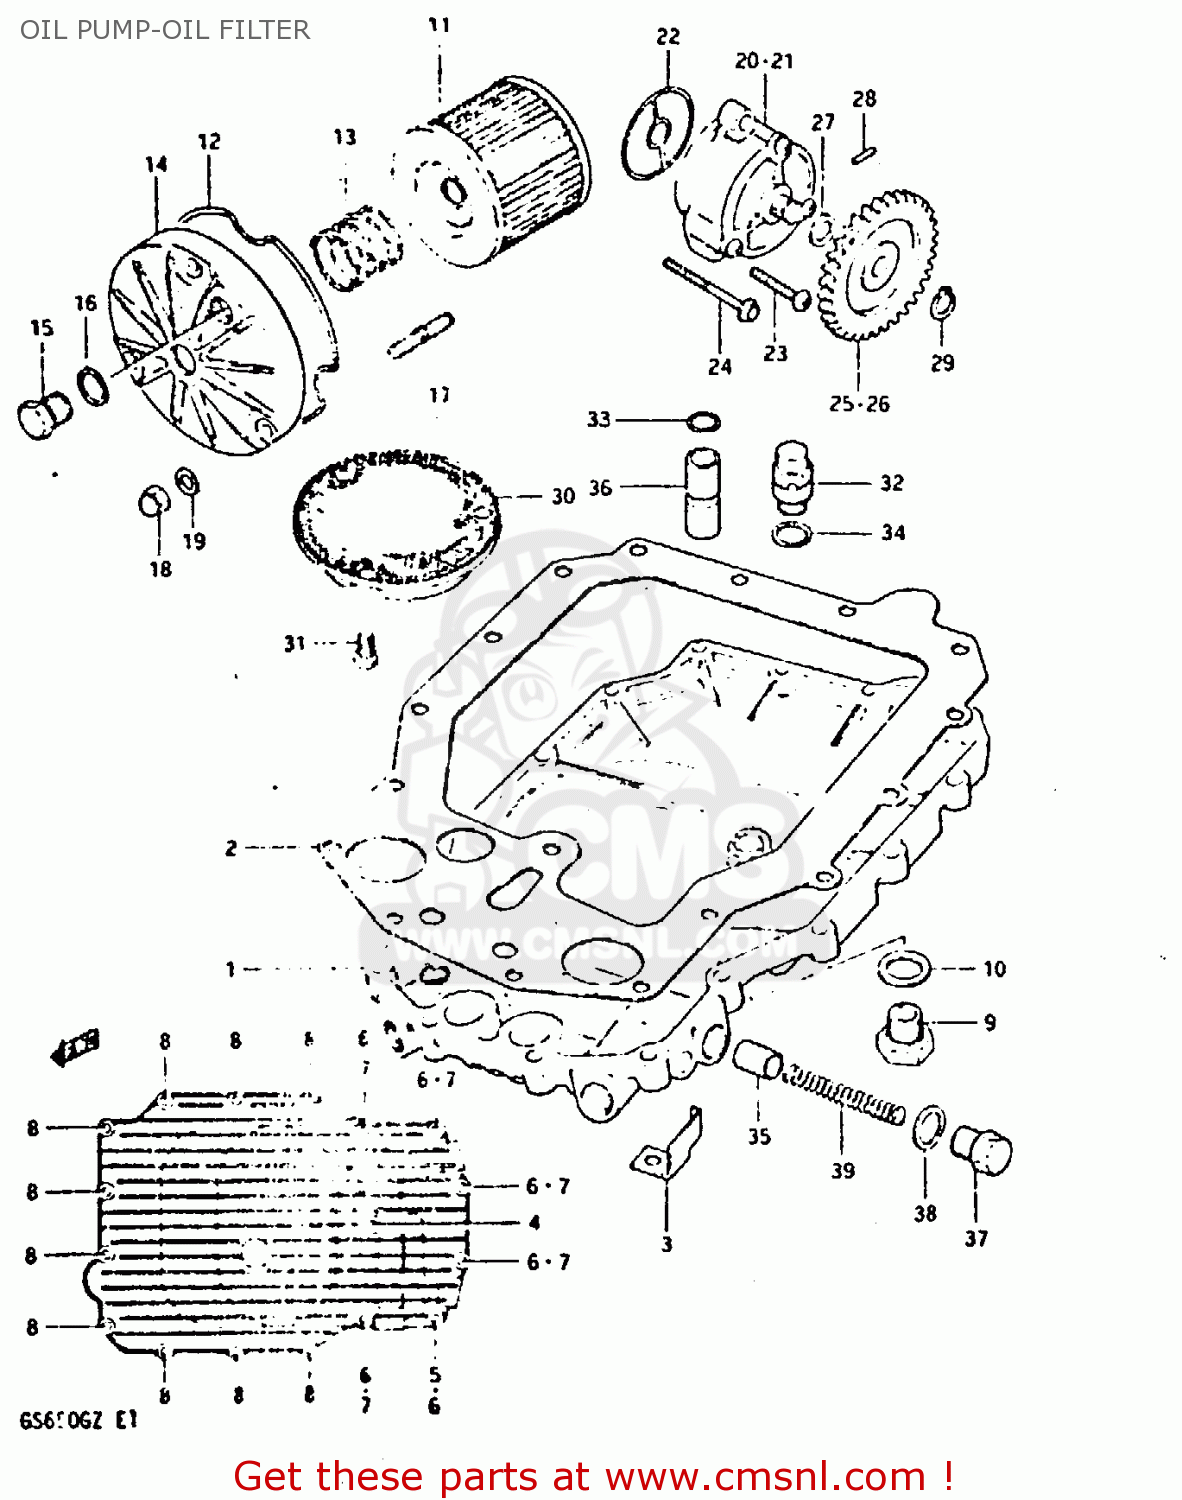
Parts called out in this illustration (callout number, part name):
1	PAN, OIL
2	GASKET,OIL PAN (MCA)
3	PLATE, OIL PAN
4	BOLT 6X35
5	BOLT
6	BOLT
7	BOLT
8	BOLT
9	PLUG
10	GASKET(14X19.2X2) (NAS)
11	FILTER ASSY,ENGINE OIL
12	O RING,OIL FILTER CHAMBER CAP
13	SPRING
14	CAP,OIL FILTER
15	PLUG
16	GASKET(14X19.2X2) (NAS)
17	STUD 6X20
18	NUT
19	WASHER
20	PUMP ASSEMBLY,OIL
21	PUMP ASSEMBLY,ENGINE OIL
22	O-RING,OIL PUMP
23	SCREW
24	BOLT
25	GEAR,OIL PUMP DRIVEN
26	GEAR,OIL PUMP DRIVEN
27	SHIM
28	PIN(4X15.8)
29	CIRCLIP
30	STRAINER,ENGINE OIL
31	SCREW 6X12
32	REGULATOR ASSEMBLY,ENGINE
33	O-RING
34	WASHER
35	PLUNGER,CONTROL
36	BY-PASS,OIL REGULATOR
37	PLUG
38	GASKET(16X22X2) (NAS)
39	SPRING
